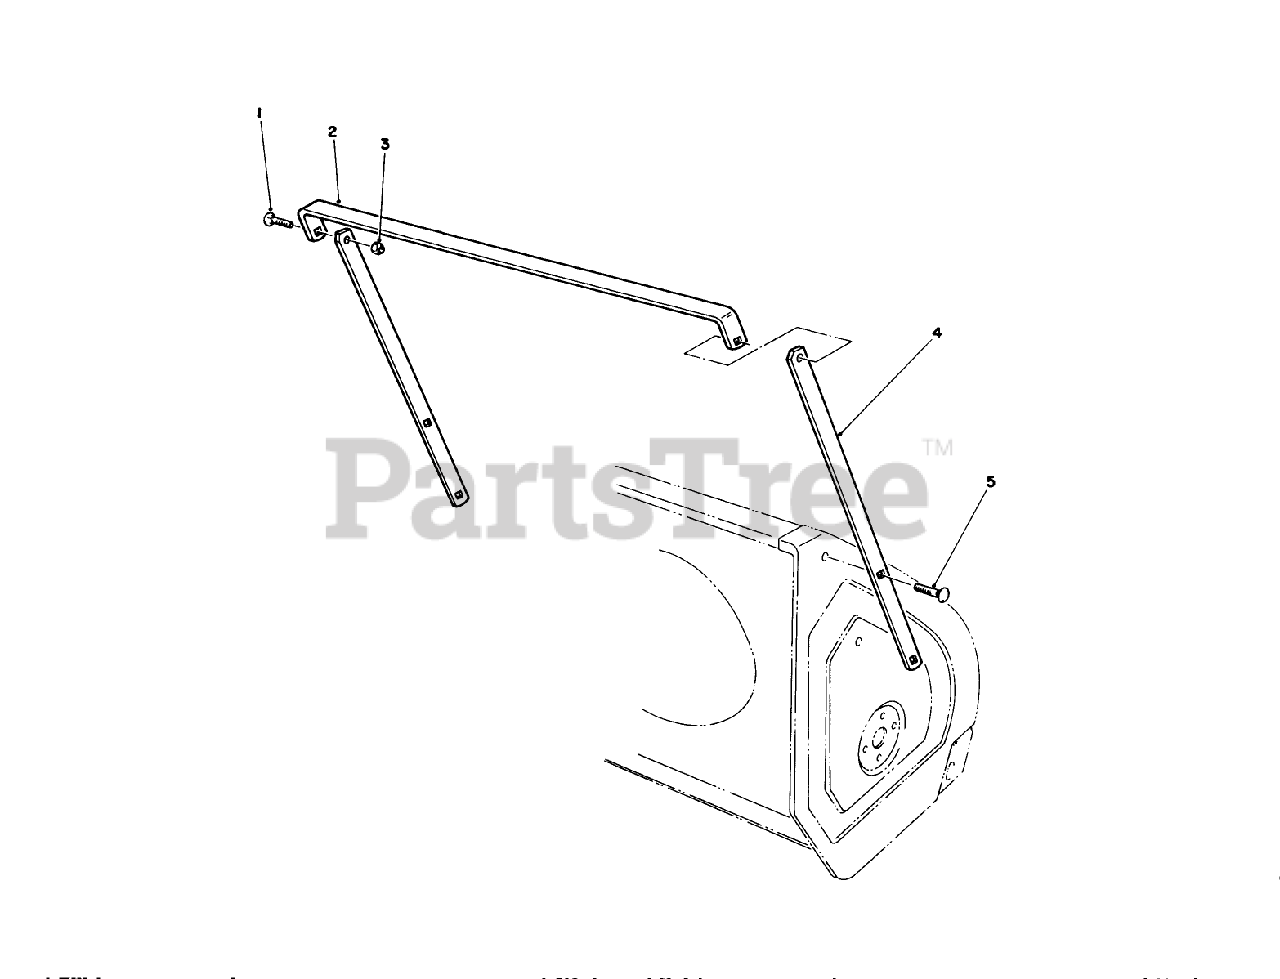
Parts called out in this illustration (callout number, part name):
1	SCREW-CARR
3	NUT-LOCK, NI
4	Breaker-Side
5	BOLT-CARR
